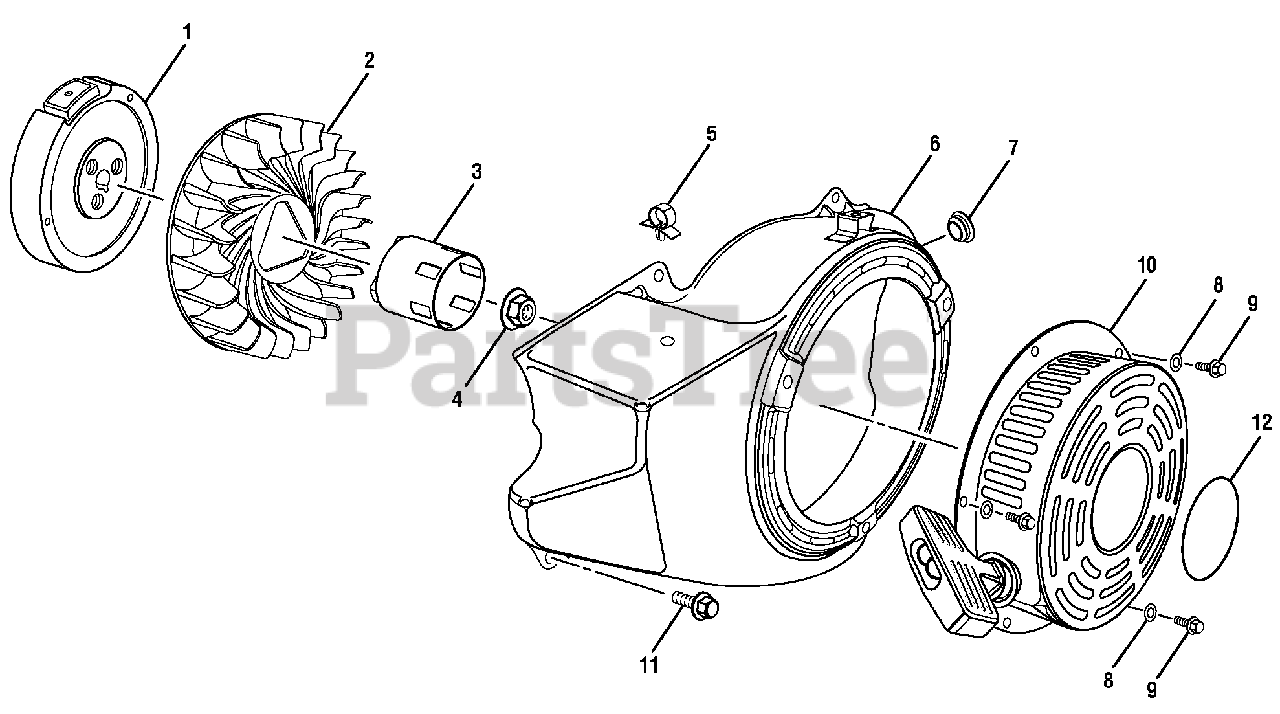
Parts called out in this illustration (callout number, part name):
2	Flywheel Fan
3	Starter Cup
4	Nut (M14 x 1.5 mm)
5	O-Ring (Fan Case)
6	Fan Case Assembly
7	Grommet (Fan Case)
8	Washer (M6)
9	Bolt (M6 x 8 mm, Flange Hd.)
10	Recoil Starter Assembly
11	Bolt (M6 x 12 mm, Flange Hd.)
12	Engine Recoil Label
